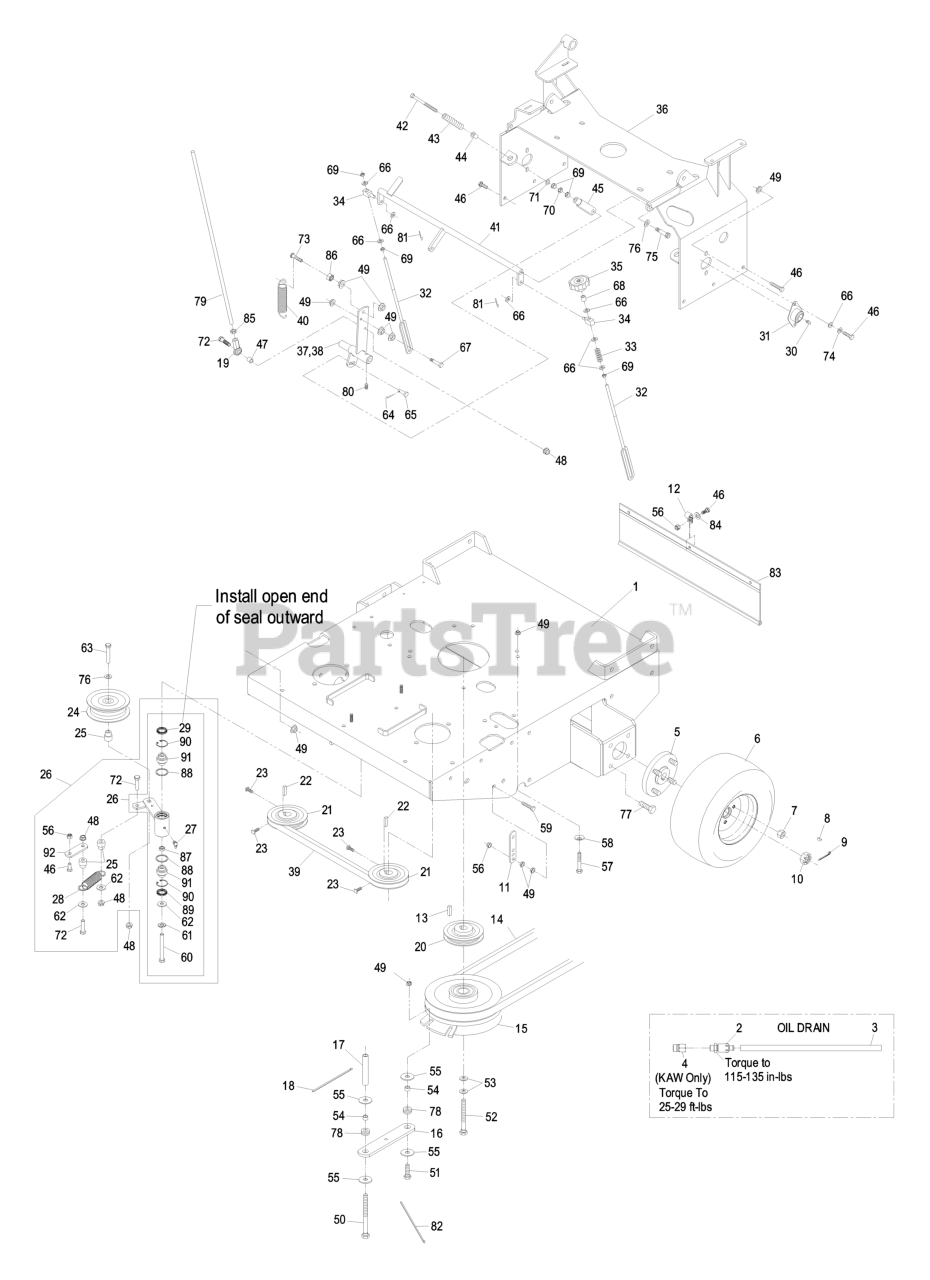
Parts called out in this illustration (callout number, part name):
1	Eng Deck 109-2579-01 W/ Decals
2	VALVE-DRAIN, OIL
3	TUBE-DRAIN, OIL
4	ADAPTER
6	ASM, DRIVE TIRE
7	NUT-LUG
8	KEY-WOODRUFF
9	PIN-COTTER
10	NUT-HEX, SLOTTED
11	TAB-SPRING, EXTENSION
12	CLIP-LOOM
14	BELT,B 83.65
15	CLUTCH ASM
16	STRAP-CLUTCH, BRAKE
17	SPACER,SHIELD
18	TIE-CABLE
19	JOINT-BALL END, LH
20	PULLEY
21	SHEAVE ASM
23	SCREW-SET
25	BUSHING-IDLER
26	KIT,IDLER ARM W/BRGS.
27	FITTING-GREASE, 90 DEG
28	SPRING-EXTENSION
29	SEAL-LIP, SINGLE
30	FITTING-GREASE
31	BEARING-FLANGE, SIDE
32	LINK,SPEED CONTROL
33	SPRING-COMPRESSION
35	KNOB-TRACKING
37	WLD,LH CONTROL ARM
39	BELT,COG A-59.5
40	SPRING-EXTENSION
41	WLD,CRANK SPEED CNTRL
42	BOLT-RETURN, NEUTRAL
43	SPRING,COMPRESSION (NEUT)
44	BUSHING-FLANGED
45	YOKE-ADJUSTABLE
46	SCREW-HH
47	TUBE,PUMP LINK SPACER
48	NUT-HHF, WHIZ
50	SCREW-HH
51	SCREW-HH
52	SCREW-HH
53	WASHER-SPRING
56	NUT-LOCK, NI
57	SCREW-HH
58	WASHER-SPRING
59	BOLT-TAP, HH
60	SCREW-HH
61	WASHER-LOCK
62	WASHER-FLAT
63	SCREW-HH
64	PIN-COTTER
65	PIN-CLEVIS
66	WASHER-PLAIN
67	SCREW-HH
69	NUT-HEX
70	NUT-JAM
71	WASHER-FLAT
72	SCREW-HH
73	SCREW-HH
74	WASHER-LOCK
75	SCREW-HSH
76	WASHER-FLAT
77	SCREW-HHF
78	GROMMET
79	LINK,DRIVE (PLTD)
80	SCREW-SET
81	PIN-COTTER
82	TIE-PLASTIC
83	SHIELD,DRAG
84	WASHER-FLAT
85	NUT-HEX JAM, LH
86	NUT-JAM
89	SEAL-LIP, DOUBLE
90	RING-SNAP
91	BEARING-SPHERICAL
92	ARM-LIFT, DECK
